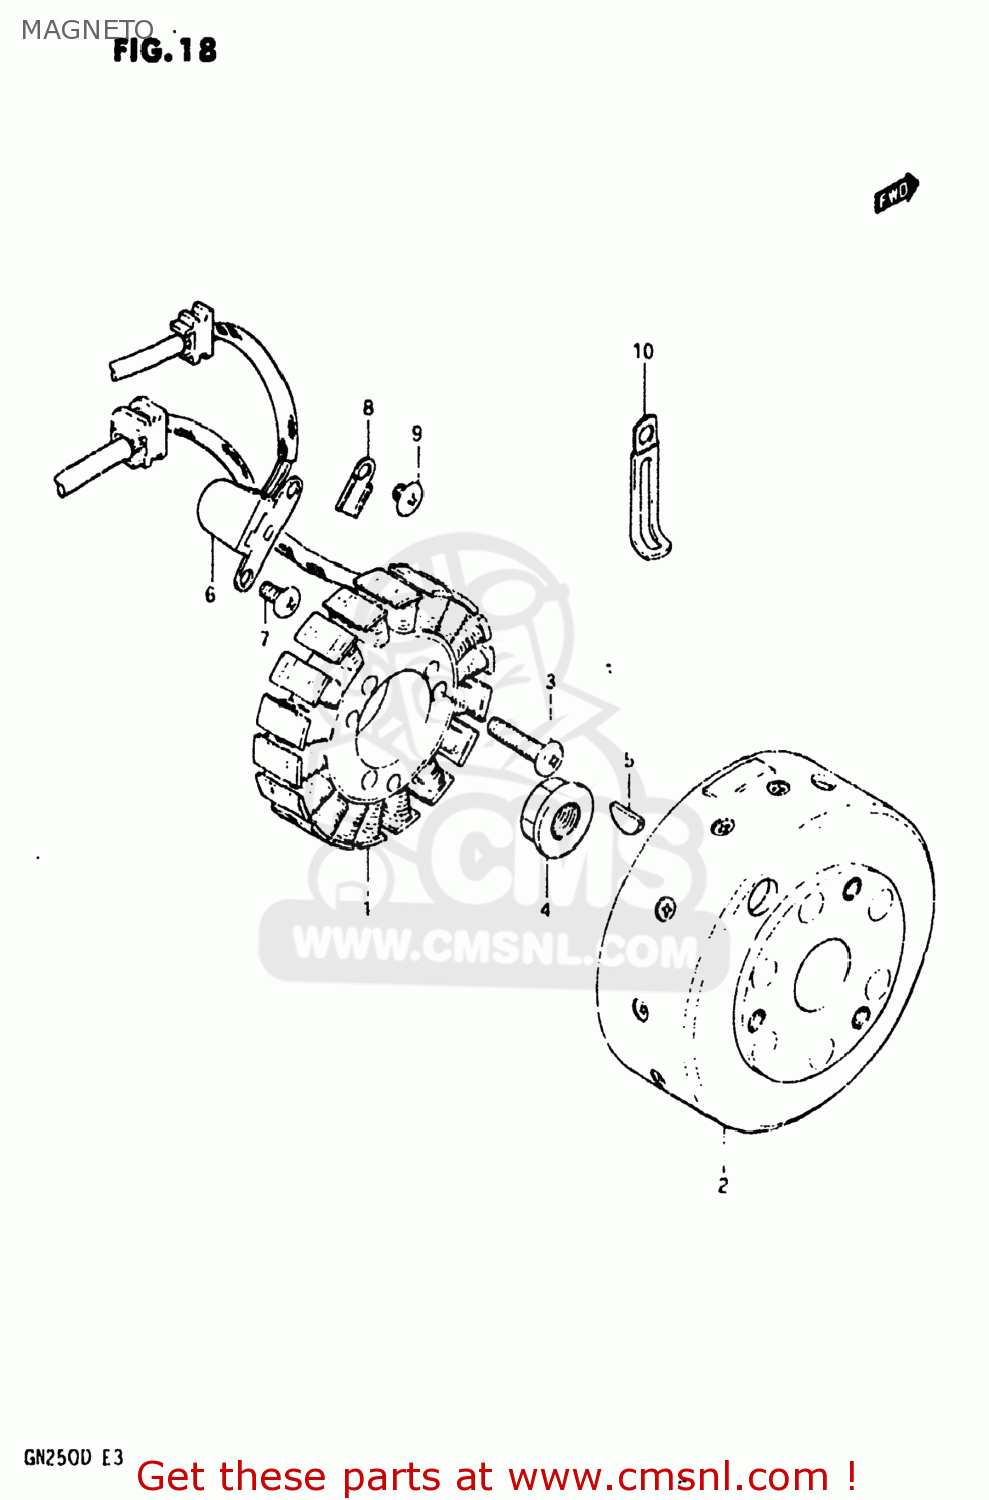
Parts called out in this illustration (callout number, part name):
1	STATOR ASSEMBLY
2	ROTOR ASSEMBLY
3	SCREW 6X30
4	NUT,GENERATOR ROTOR
5	KEY
6	COIL ASSY,PICK UP
7	SCREW
8	CLAMP,GENERATOR LEAD WIRE
9	SCREW 5X6
10	CLAMP L:35
